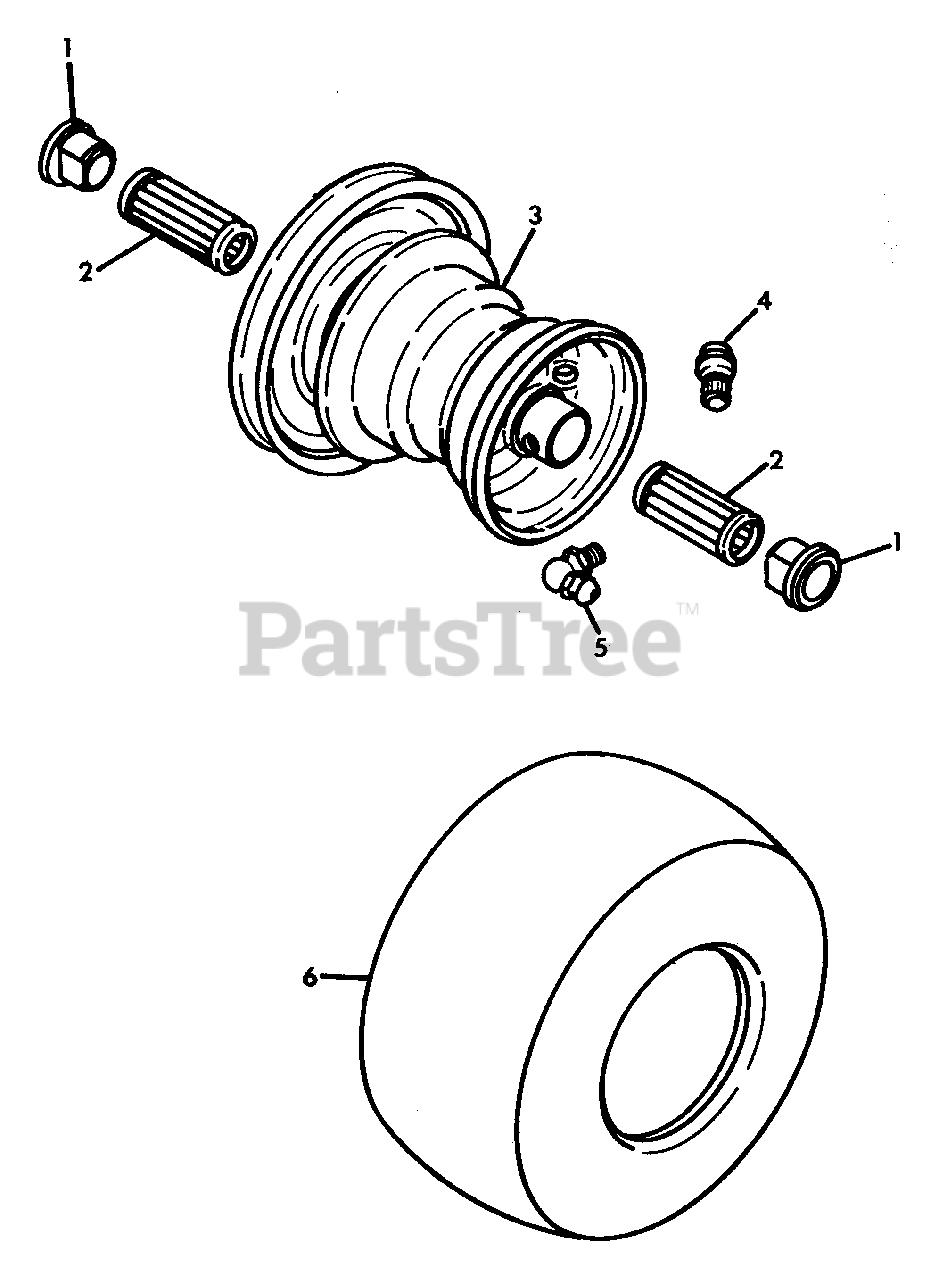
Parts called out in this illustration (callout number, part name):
1	Bearing, Flange
2	Bearing, 7/8x2.50
3	Rim
4	Assembly, Valve Stem
5	Fitting, Lube 90 Deg.
6	Tire, 13x6.50-6
